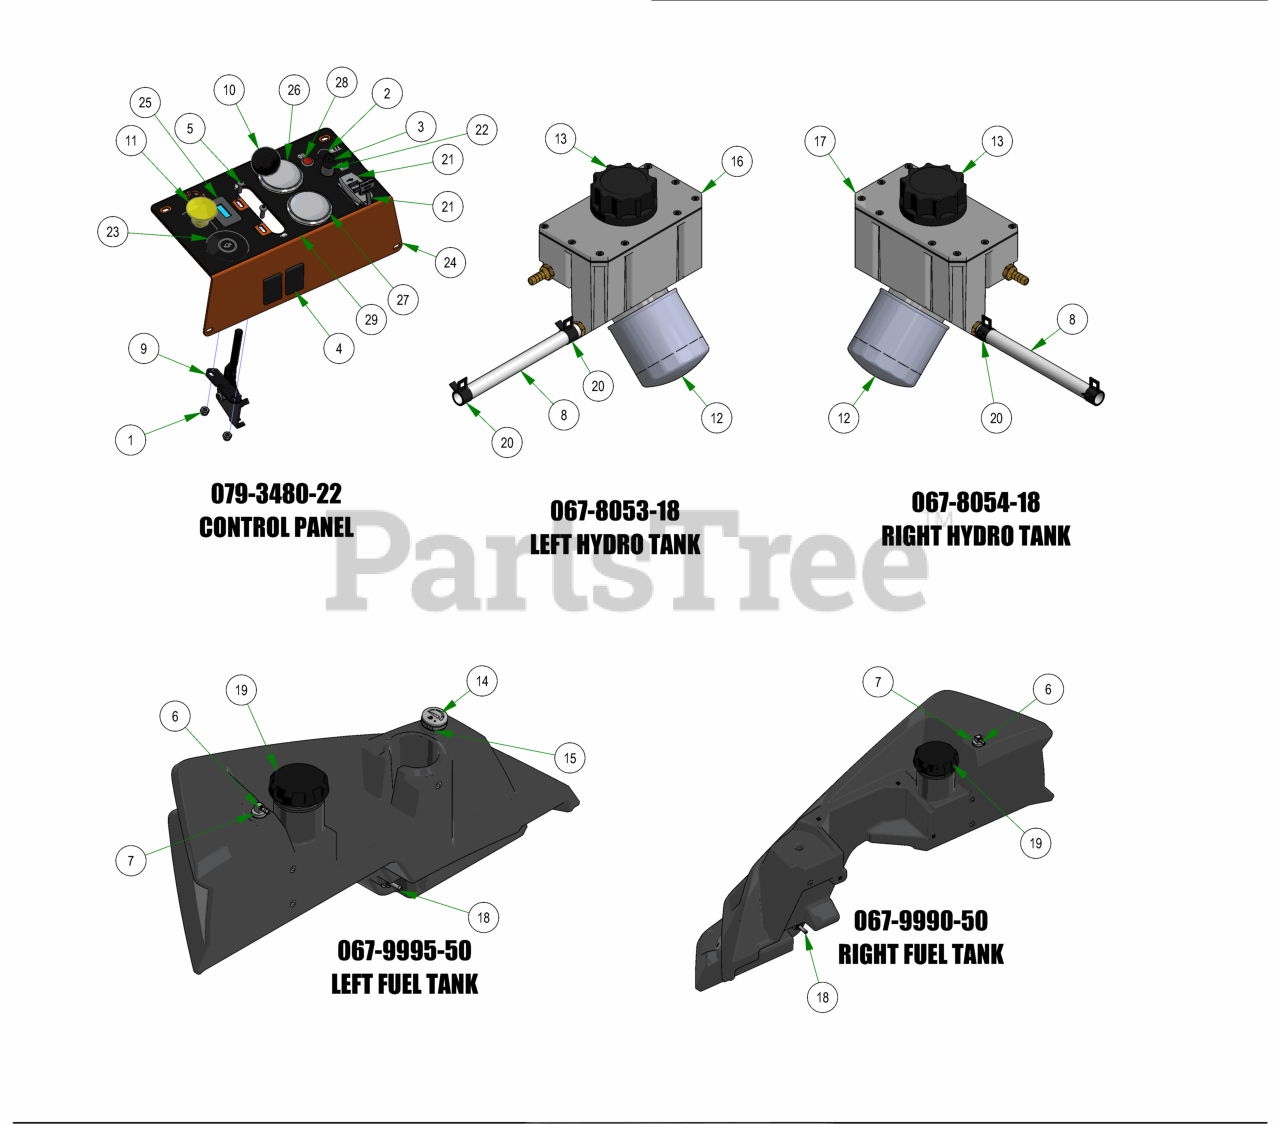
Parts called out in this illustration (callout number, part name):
1	10-24 NYLON INSERT LOCKNUT ZINC
2	5/8 Round Insert
3	Start Switch Boot - Diesel
4	Light Plug
5	10-24 X 5/8 BUTTON SOCKET CAP SCREW 18-8 STAINLESS STEEL
6	90 Degree Elbow Fitting
7	Nitrile Bushing
8	1/2 Clear Braded Hose 21"
9	Universal Throttle Head - 2012
10	Throttle Knob
11	PTO Switch
12	Hydraulic Filter
13	Hydraulic Tank Cap W/Dipstick
14	Fuel Gauge
15	Fuel Gauge Grommet
16	2019 Left Outlaw Gen2 Hydro Tank Suspension Only
17	2019 Right Outlaw Gen2 Hydro Tank Suspension Only
18	Fuel Pick-up
19	Diesel Fuel Cap
20	1/2 Hose Clamp
22	Momentary Start Switch
23	Ignition Switch
24	2019 Diesel Control Panel
25	Tachometer
26	2" Oil Pressure Gauge
27	2" Water Temperature Gauge
29	2022 Renegade (Diesel) Control Panel Decal
